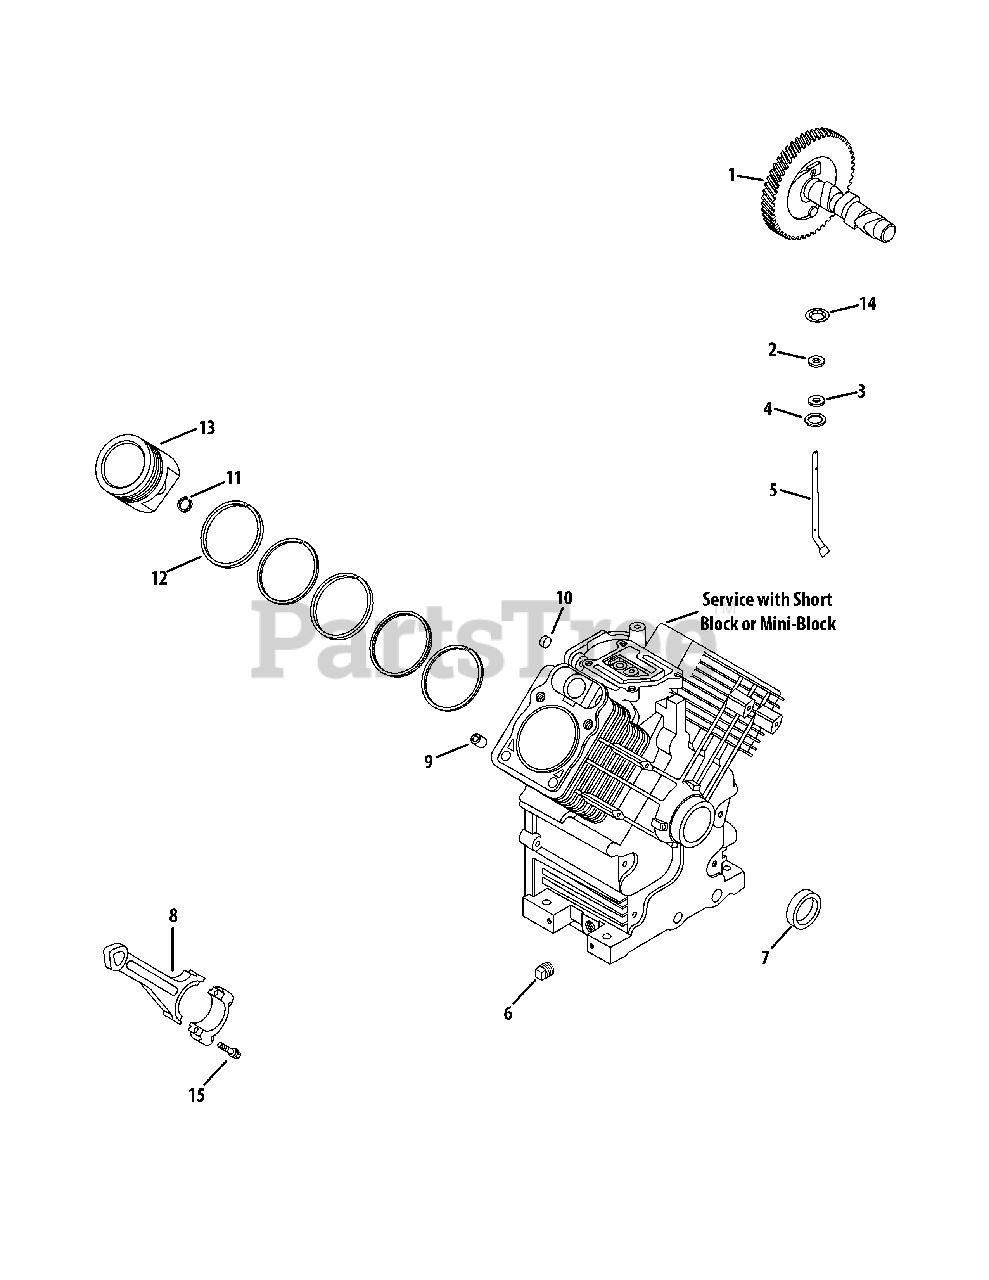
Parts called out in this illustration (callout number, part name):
1	Camshaft Kit
2	Flat Washer, 9 MM
3	Governor Cross Shaft Seal
4	Flat Washer, 11/32
5	Governor Cross Shaft
6	Square Headd Pipe Plug, 3/8
7	Oil Seal (Helix Lip)
8	Connecting Rod Assembly
11	Piston Pin Retainer
12	Ring Set (Std)
12	Ring Set (.08)
12	Ring Set (.25)
12	Ring Set (.50)
13	Piston Assembly Kit w/ Ring (Std.)
13	Piston Assembly Kit w/ Ring Set (.08)
13	Piston Assembly Kit w/Ring Set (.25)
13	Piston Assembly Kit w/ Ring Set (.50)
14	Ring Retainer
15	Rod Bolts Kit
